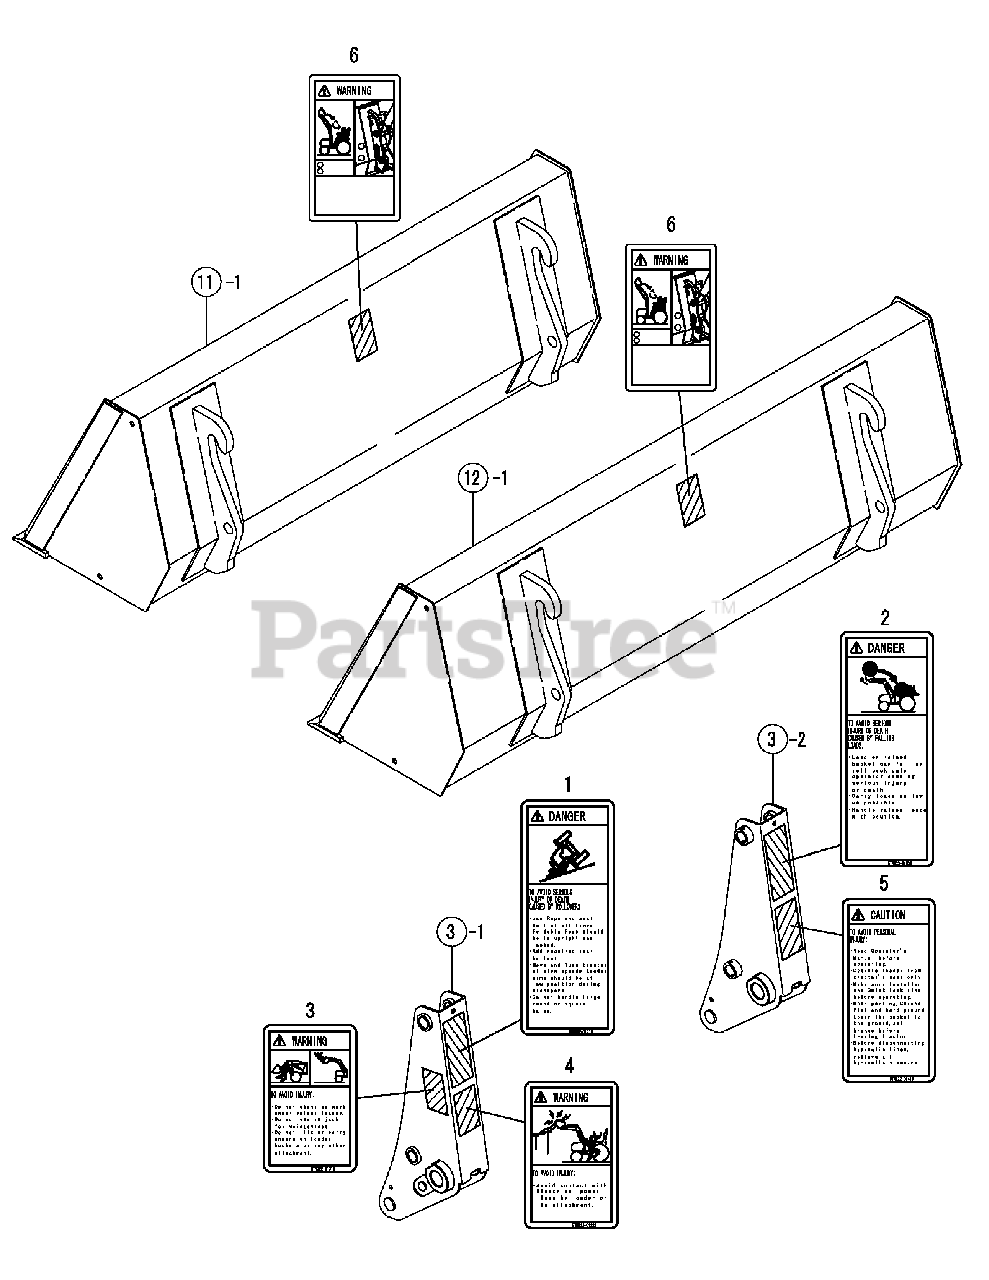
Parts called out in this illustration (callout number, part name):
1	Label,Danger,Roll
2	Label,Danger,Fall
3	Label,Warning
4	Label,Warning,Shock
5	Label,Caution
6	Label, Warning,Quick
